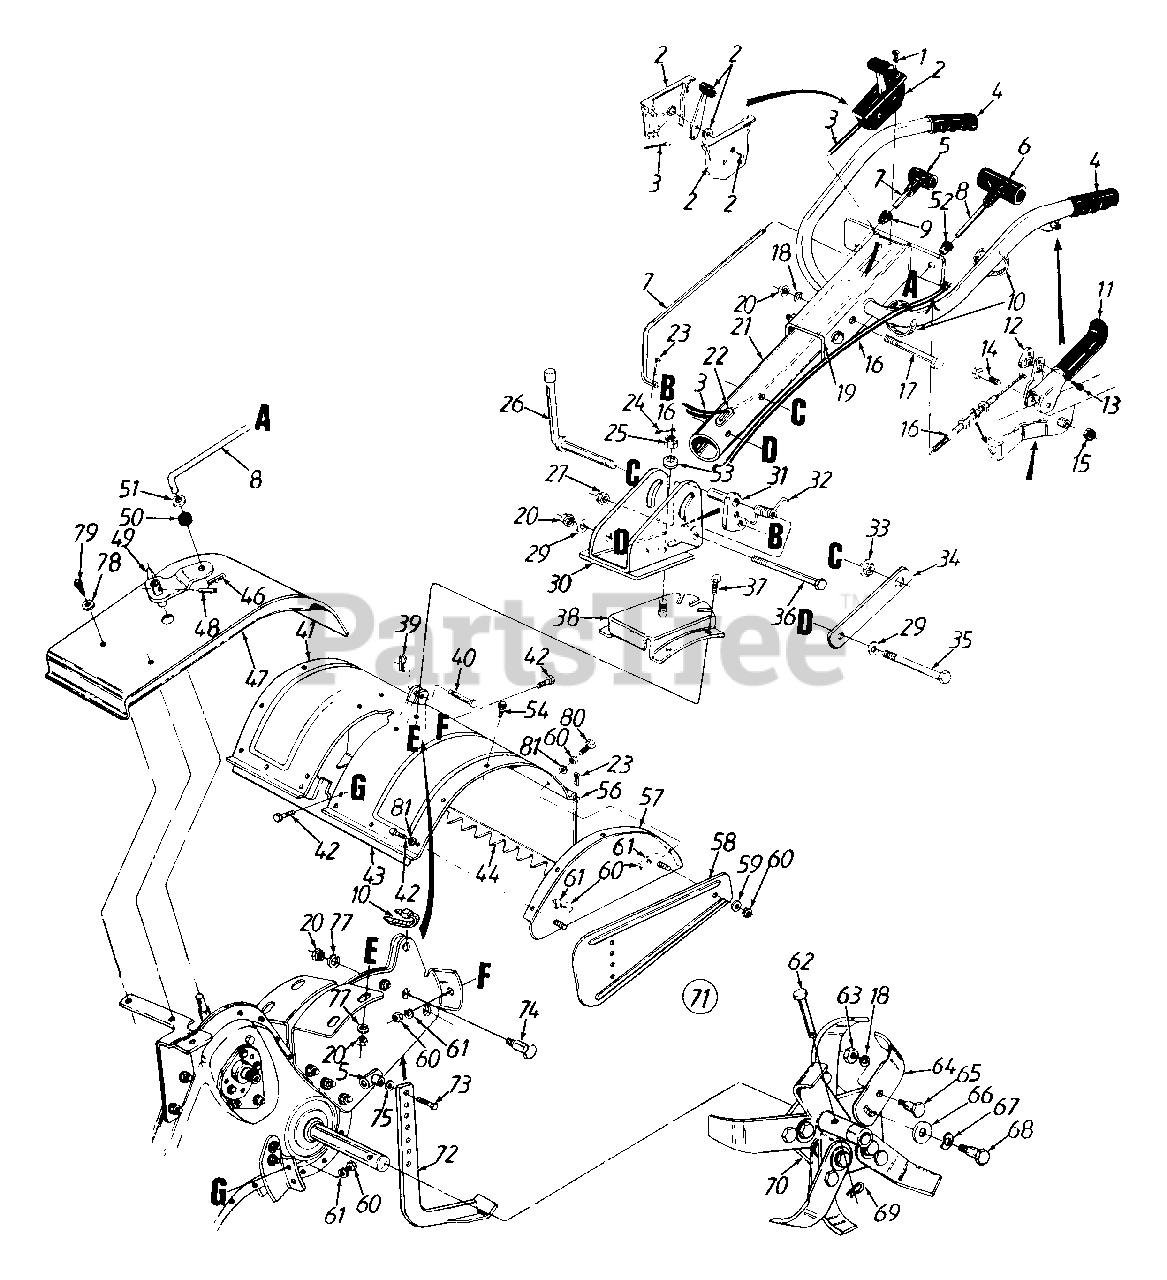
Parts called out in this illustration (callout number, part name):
1	Truss Mach. AB - Tap. Scr. #10 x .50" Lg.
2	Throttle Control Box Ass'y.
3	Throttle Control Wire
4	Handle Grip
5	Small "T" Knob
6	Large "T" Knob
7	Clutch Rod
8	Control Rod 37" Lg.
9	Snap On Bushing 3/8" Dia.
10	Cable Tie-Self Clinching
11	Clutch Grip Ass'y. - L.H.
12	Barrel Cable Hold Down
13	Hex B-Tap Scr. #10 x .44" Lg.
14	Hex Bolt 3/8-24 x 2.25" Lg.
15	Hex Jam L-Nut 3/8-24 Thd.
16	Clutch Control Cable 46" Lg.
17	Hex Bolt 3/8-16 x 3.00" Lg.
18	L-Wash. 3/8" I.D. - H.D.
23	Cotter Pin 3/32" Dia. x .75" Lg.
24	Cotter Pin 3/32" Dia. x 1.25" Lg.
25	Hex Slotted Nut 5/8-18 Thd.
26	Handle Adj. Crank
27	Hex Cent. L-Nut 3/8-16 Thd.
29	Bell-Wash..4" I.D. x .87" O.D.
30	Handle Pivot Bracket
31	Positioner Crank Ass'y.
32	Spring Handle Adj. Torsion
33	Hex Flange Nut 3/8-24 Thd.
34	Bracket Hex Nut Retainer
35	Hex Bolt 3/8-16 x 3.25" Lg.
36	Hex Bolt 3/8-16 x 3.00" Lg. - Gr. 8
37	Hex Bolt 3/8-16 x 1" Lg.
40	Clevis Pin .375" Dia.
43	Bracket Reinforcement - 18"
46	Intern Cotter Pin 5/16" Dia.
49	Shifting Crank Ass'y.
50	Rubber Washer 33" I.D
51	Fl-Wash. 4" I.D. x 1.25" O.D.
52	Snap On Bushing 1/2" Dia.
53	Bell-Wash 63" I.D. x 1.25"
54	Hex Wash. Tap Scr
56	Tiller Flap Rod
57	End Cover Ass'y
60	Hex Nut 5/16-18 Thd.
61	L-Wash 5/16" I.D.
62	Clevis Pin .375" Dia.
63	Hex Nut 3/8-24 Thd.
64	13" Dia. Articulating Tine
65	Shld. Bolt 1/2" Dia. x .175
66	Fl-Wash 51" I.D. x 1.50"
67	Bell-Wash .515" I.D. x 1.14"
68	Shld. Bolt 1/2" Dia. x .320
69	Intern. Cotter Pin
70	Tine Adapter Ass'y. 18"
71	Tine Ass'y. Comp. 18"
72	Depth Bar
73	Hex Bolt 3/8-16 x .75" Lg.
74	Shld. Bolt 1/2" I.D x .62" Lg.
75	Fl-Wash 3/8" I.D. x 5/8" O.D.
77	L-Wash. 3/8" I.D.
78	Fl-Wash .281" I.D x .62"
79	Hex Wash Self-Tap Scr. 1/4-20 x .50" Lg
80	Hex Bolt 5/16-18 x 11/4" Lg.
81	Cap L-Nut 5/16-18 Thd.
